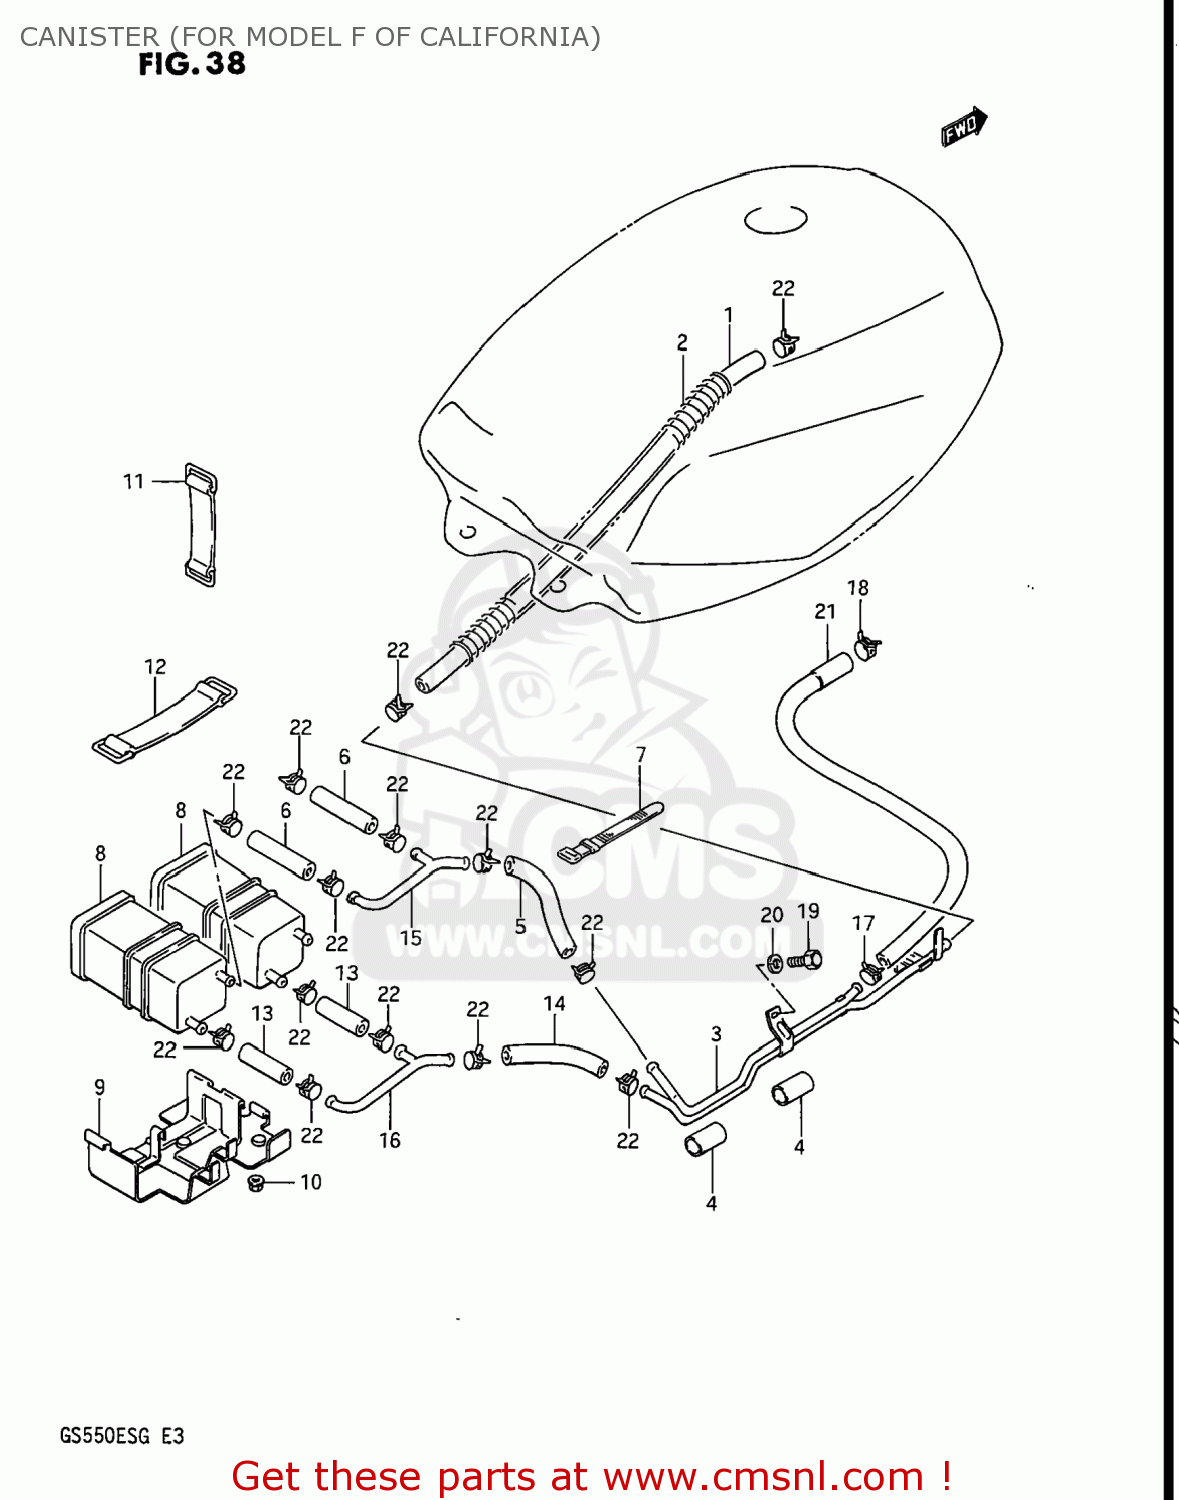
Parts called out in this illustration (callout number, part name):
1	HOSE
2	SPRING
3	PIPE
4	PIPE
5	HOSE
6	HOSE
7	CLAMP(L:187)
8	(CA) CANISTER ASSEMBLY
9	BRACKET,CANISTER
10	NUT
11	BAND
12	BAND
13	HOSE
14	HOSE
16	PIPE CANISTER
17	CLIP
18	CLAMP
19	BOLT
20	WASHER
21	HOSE
22	CLIP
